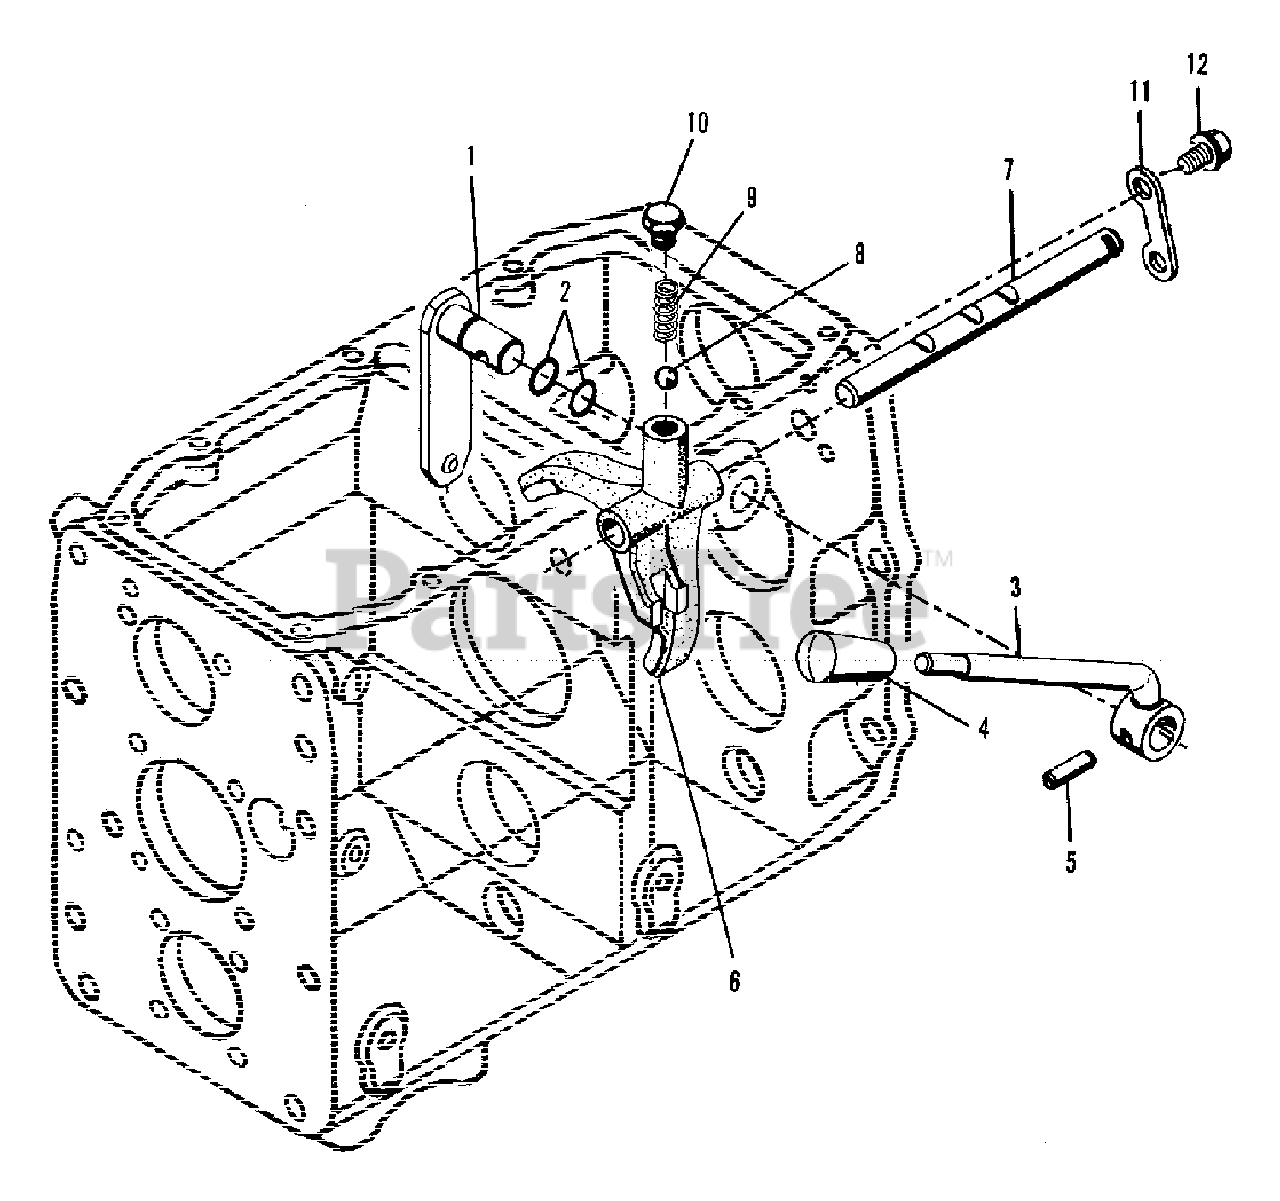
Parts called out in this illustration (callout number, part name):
1	LEVER, shift
3	LEVER ASSEMBLY, control (Incl. Item 4)
4	KNOB, control lever, green
5	PIN, M8 x 28 lock
6	FORK, hi & lo range
7	ROD, shifter, hi & lo range
8	BALL, detent
9	SPRING, detent
10	SCREW, detent
11	STOPPER, shifter rod
12	CAPSCREW, M10 x 20 w/lockwasher
